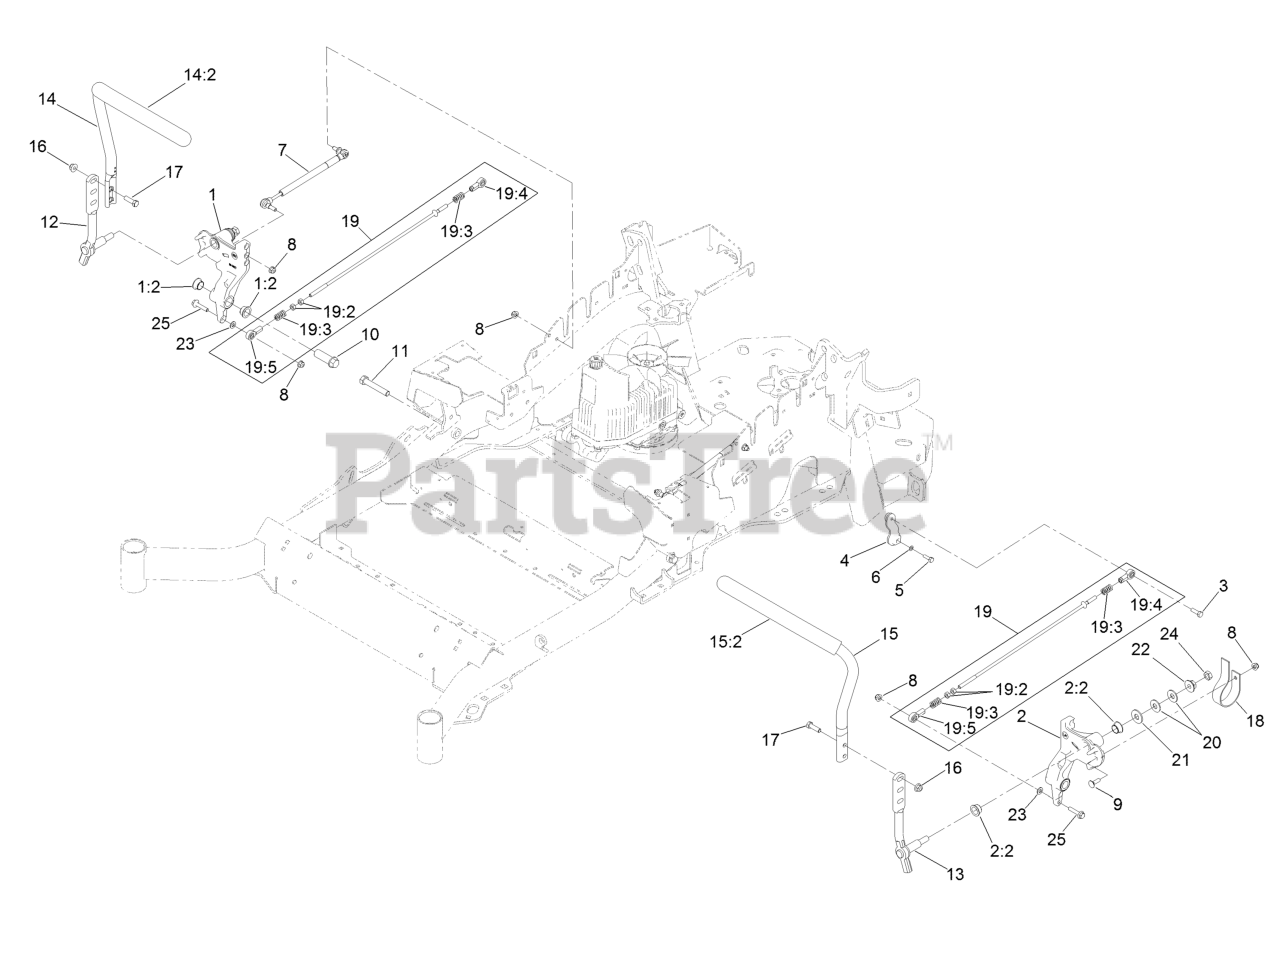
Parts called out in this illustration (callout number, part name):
1	RH Motion Control And Bushing ASM
1:2	Bushing-Flange
2	LH Motion Control And Bushing ASM
2:2	Bushing-Flange
3	Screw-HH, Thread Locking
4	Arm-Control, Pump
5	Screw-HH
6	Washer-Spring
7	Damper-Control, Motion
8	Nut-HF, NI
9	Bolt-CARR
10	Hub-Threaded
11	Screw-HH
12	Lever-Control Motion, RH
13	Lever-Control Motion, LH
14	RH Steering Handle ASM
14:2	Grip-Control, Lever
15	LH Steering Handle ASM
15:2	Grip-Control, Lever
16	Nut-HF, NI
17	Screw-HH
18	Spring-Leaf
19	Front Pump Linkage ASM
19:2	Nut-Hex
19:3	Spring-Compression
19:4	Balljoint-LH
19:5	Balljoint-RH
20	Washer-Spring
21	Washer-Flat
23	Washer-Plain
24	Nut-Jam
25	Screw-HHF
